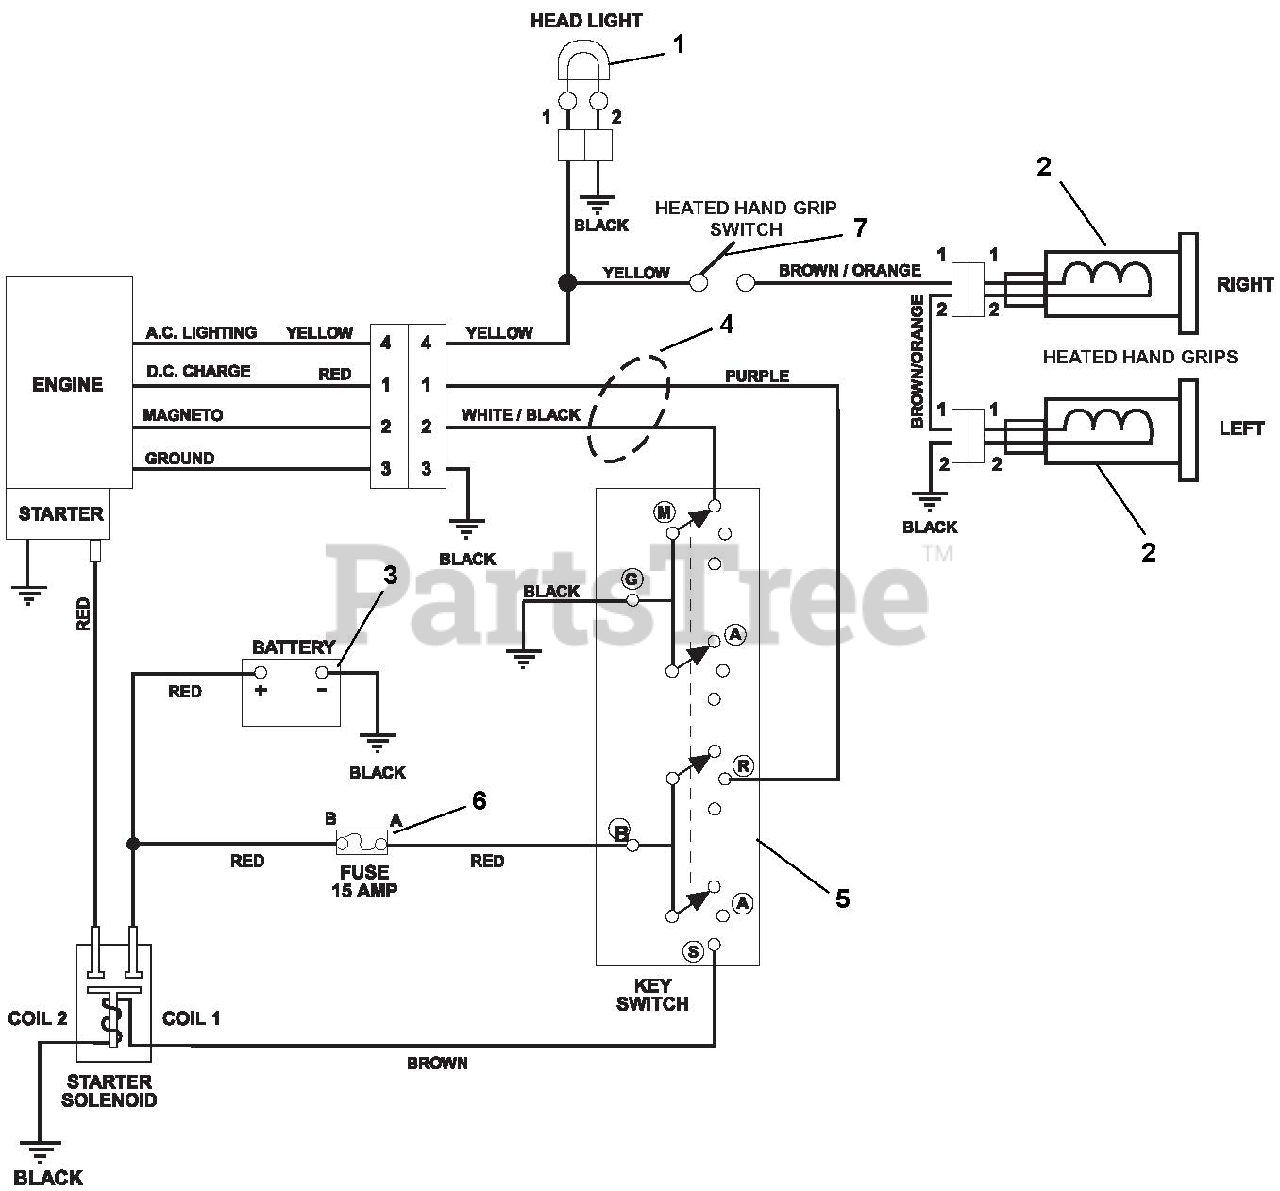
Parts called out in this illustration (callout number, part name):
1	HEADLIGHT ASY, HOLO 15W 2 SHOT
2	HEATED GRIP, MAGURA
3	Battery
4	HARNESS,BRUSH-LT,HW,12V
5	SWITCH ASSEMBLY
6	FUSE, 15 AMP.
7	SWITCH, ON/OFF
